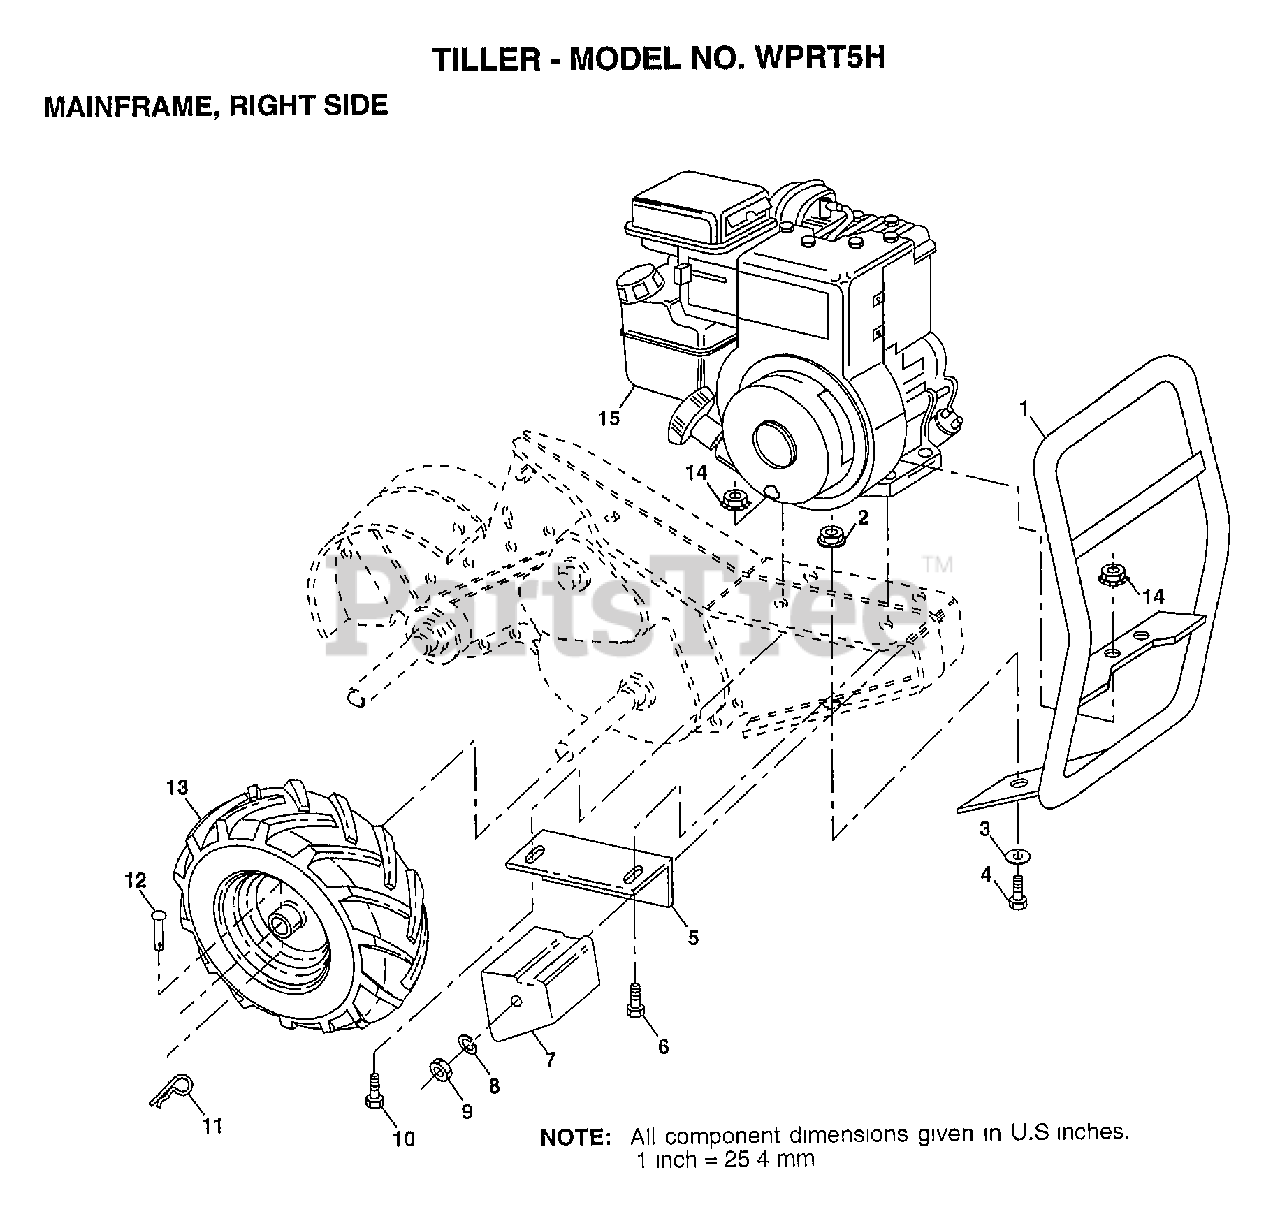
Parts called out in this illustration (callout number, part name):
1	BUMPER ASM.TILLER
2	LOCKNUT TI
3	WASHER
4	BOLT
5	BRACKET RH CRT
6	BOLT
7	COUNTERWEIGHT CRT
8	LOCKWASHER
9	NUT.HEX.3/8-16UNC
10	BOLT.HEX.5/16-1.5
11	RETAINER M
12	RIVET.DRILL.1.75
13	TIRE TI
